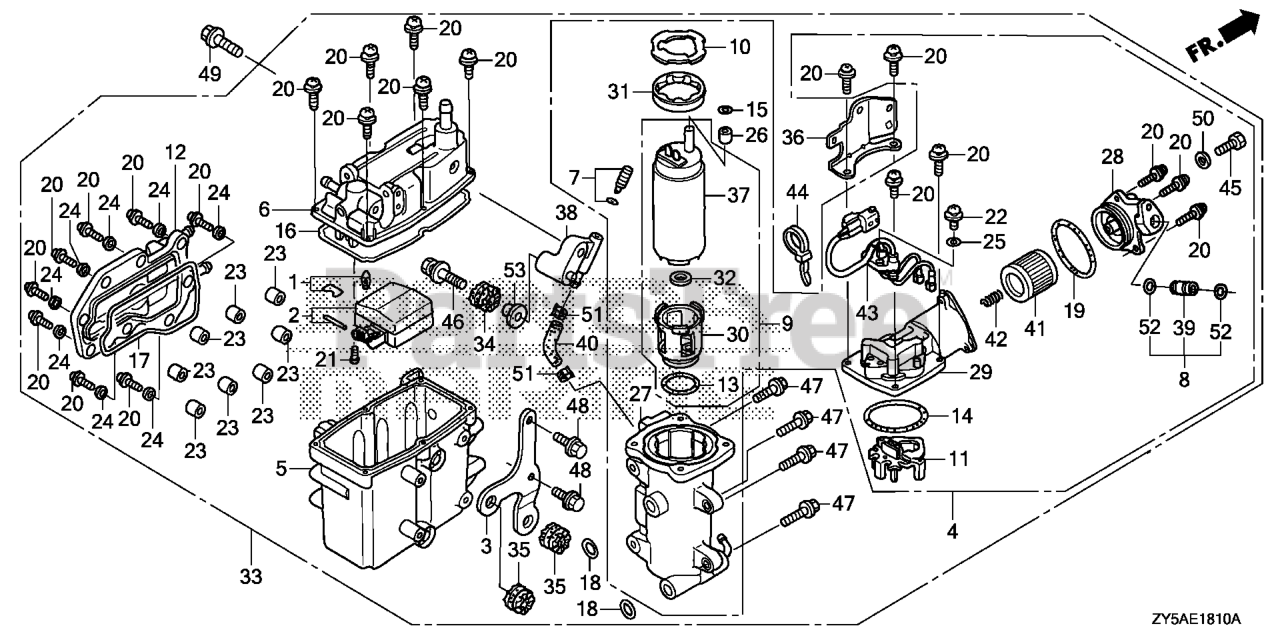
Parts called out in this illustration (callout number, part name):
1	VALVE SET, FLOAT
3	STAY A, PLATE
4	PUMP UNIT, FUEL (MSDS)
5	BODY, CHAMBER
7	SCREW SET, DRAIN (CARBURETOR NO.)
9	PUMP UNIT, FUEL (B) (MSDS)
12	COVER, WATER JACKET
15	O-RING (7.3X2.2) (NOK)
20	SCREW-WASHER
21	SCREW, PAN
22	SCREW, WASHER
23	COLLAR, SET
24	WASHER, PLAIN
25	WASHER, PLAIN
27	CASE, PUMP
28	COVER B, PUMP
29	COVER, PUMP (A)
33	SEPARATOR ASSY., VAPOR
33	SEPARATOR, VAPOR
34	GROMMET, VAPOR SEPARATOR
35	GROMMET, VAPOR SEPARATOR
36	STAY, PLATE
37	PUMP UNIT, FUEL (MSDS)
38	STAY, VAPOR SEPARATOR
39	JOINT, FUEL PIPE
40	TUBE F, FUEL
41	SCREEN, FUEL STRAINER
42	SPRING, SET
45	BOLT, SEALING (6MM)
46	BOLT-WASHER (8X35)
47	BOLT, FLANGE (6X25)
48	BOLT, FLANGE (6X16)
49	BOLT, FLANGE (8X30)
50	WASHER, SEALING (6MM)
51	CLAMP, TUBE (8.0)
52	O-RING (7.8X1.9) (ARAI)
53	COLLAR (8.5X14.5)
